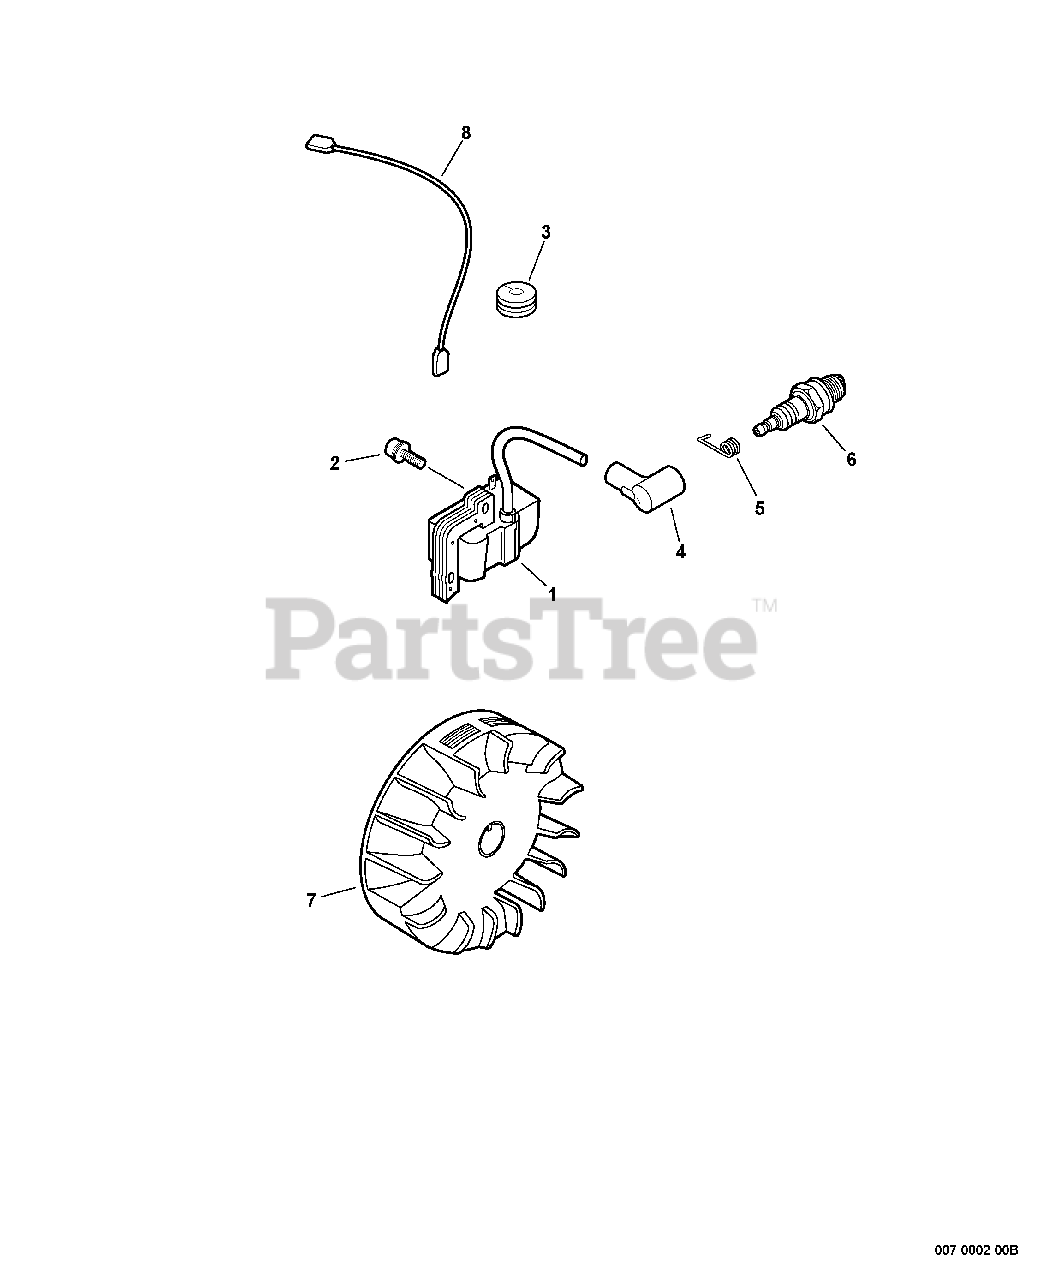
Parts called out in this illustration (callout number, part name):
1	COIL, IGNITION
2	SCREW - 4X22
3	GROMMET
4	CAP, SPARK PLUG
5	TERMINAL, SPARK PLUG CAP
6	SPARK PLUG -- BPM-7A
7	FLYWHEEL
8	LEAD - IGNITION
